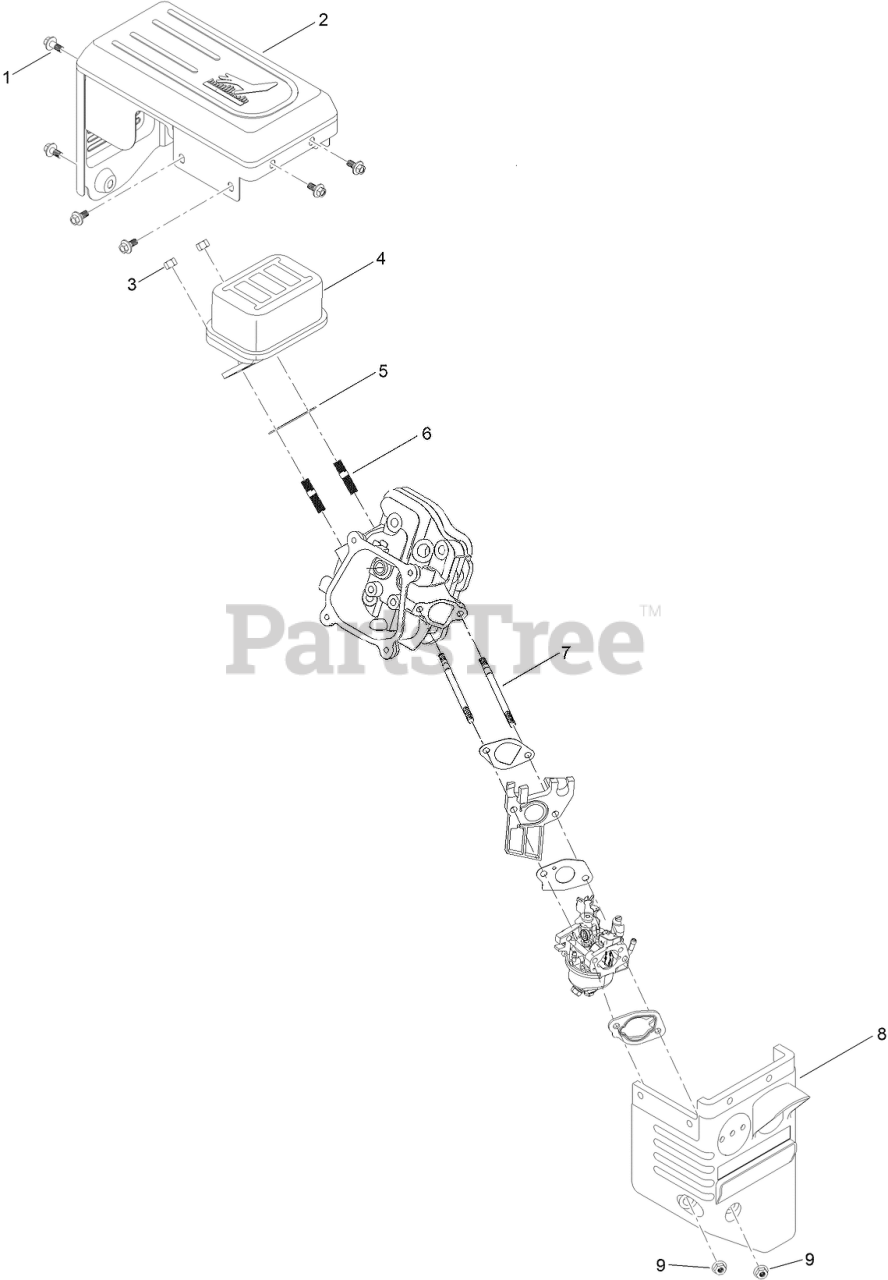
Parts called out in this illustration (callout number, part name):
1	SCREW-HHF
2	GUARD-MUFFLER
3	NUT-HH
4	MUFFLER ASM
5	GASKET-EXHAUST
6	STUD-EXHAUST
7	STUD-INTAKE
8	BOX-HEATER
9	NUT-FLANGE
